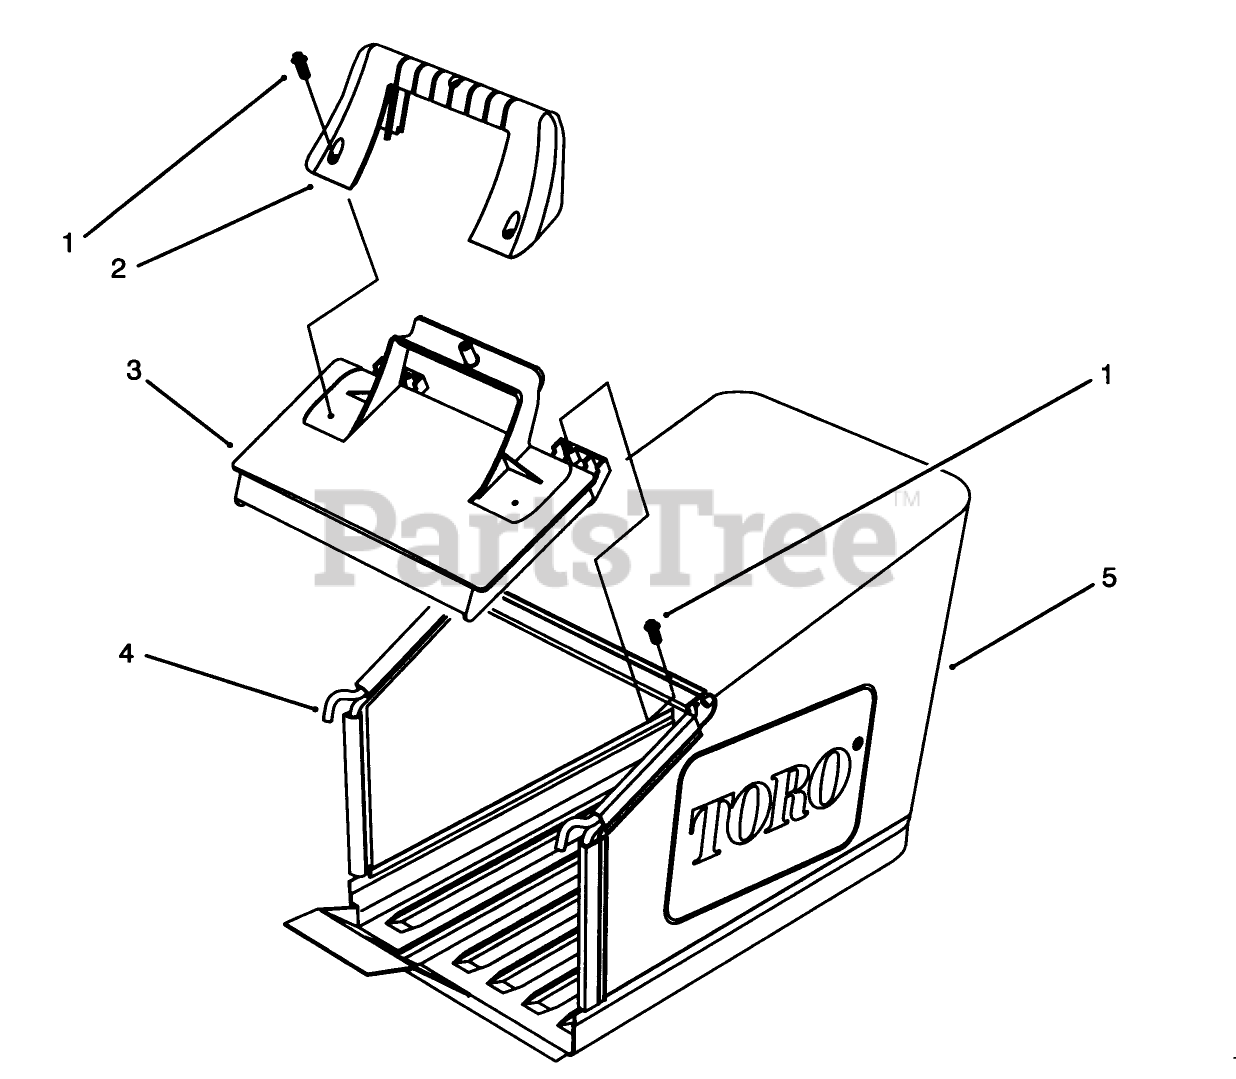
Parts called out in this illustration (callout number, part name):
1	SCREW-PPH
2	HANDLE-DOOR
3	DOOR-BAG
4	Frame
5	BAG-GRASS
